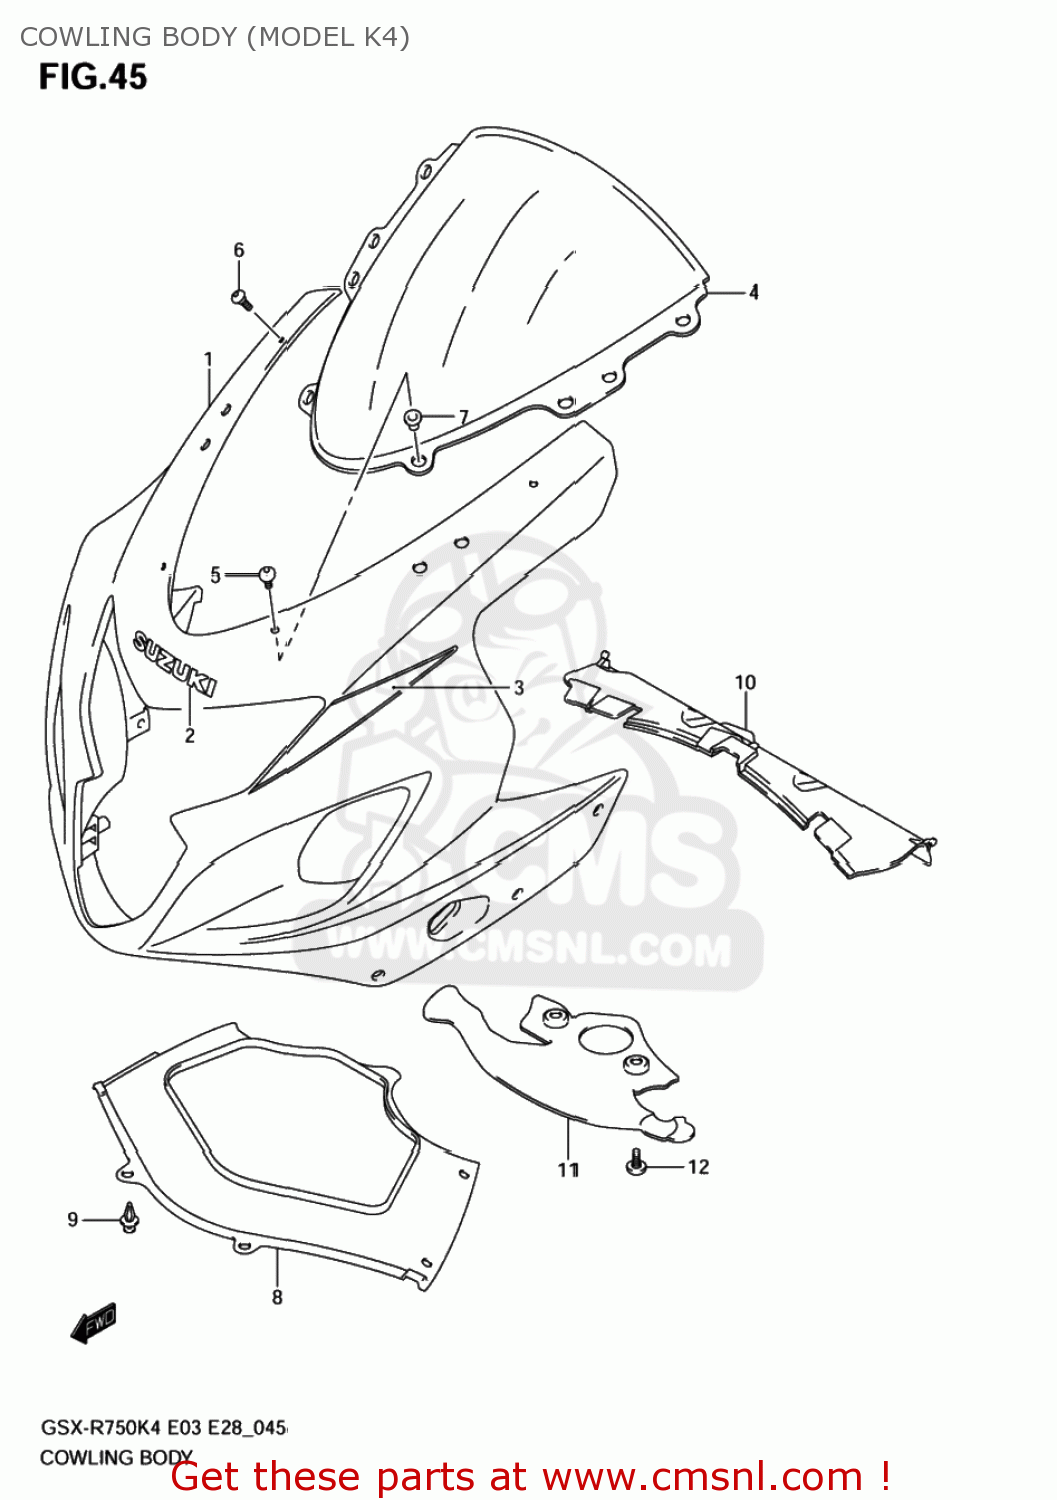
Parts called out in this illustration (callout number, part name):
1	COWLING ASSY,BODY
2	EMBLEM,SUZUKI
3	TAPE SET,COWL BODY FR
4	WINDSCREEN
5	SCREW(5X18)
6	SCREW(5X15)
7	NUT
8	COVER,BODY COW
9	CLIP(BLACK)
10	COVER,COWLING FR LWR
11	COVER,LWR BRACKET
12	BOLT
